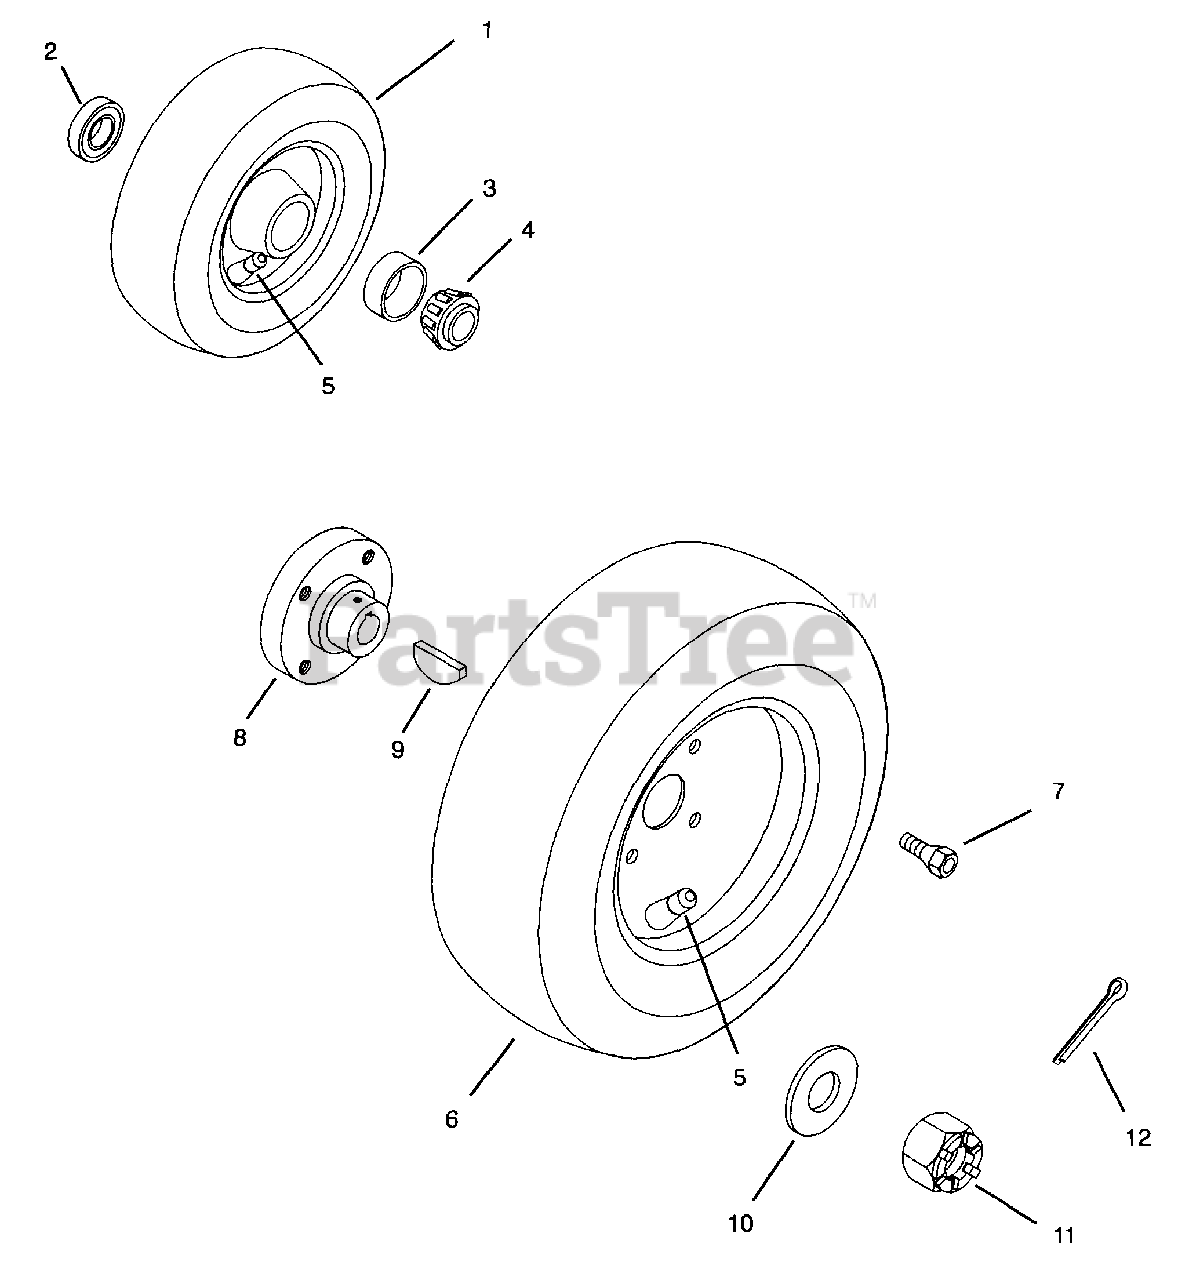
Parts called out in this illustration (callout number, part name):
1	Tire/Wheel Assembly 4.80-8
2	Seal
3	Bearing-Cup 1.980 x 4.20
4	Bearing-Cone 1.0 x .58
5	Valve Stem Assembly
6	Tire/Wheel Assembly 8.50-8 x 18
7	Bolt-Hex .50-20 x .75 x 1.62
8	Hub
9	Key-Woodruff .25 x 1.0 x 7.00
10	Washer-Flat-Steel .755 x 1.375 x .062
11	Nut-Hex-Slotted .75-20
12	Pin-Cotter .12 x 1.25
